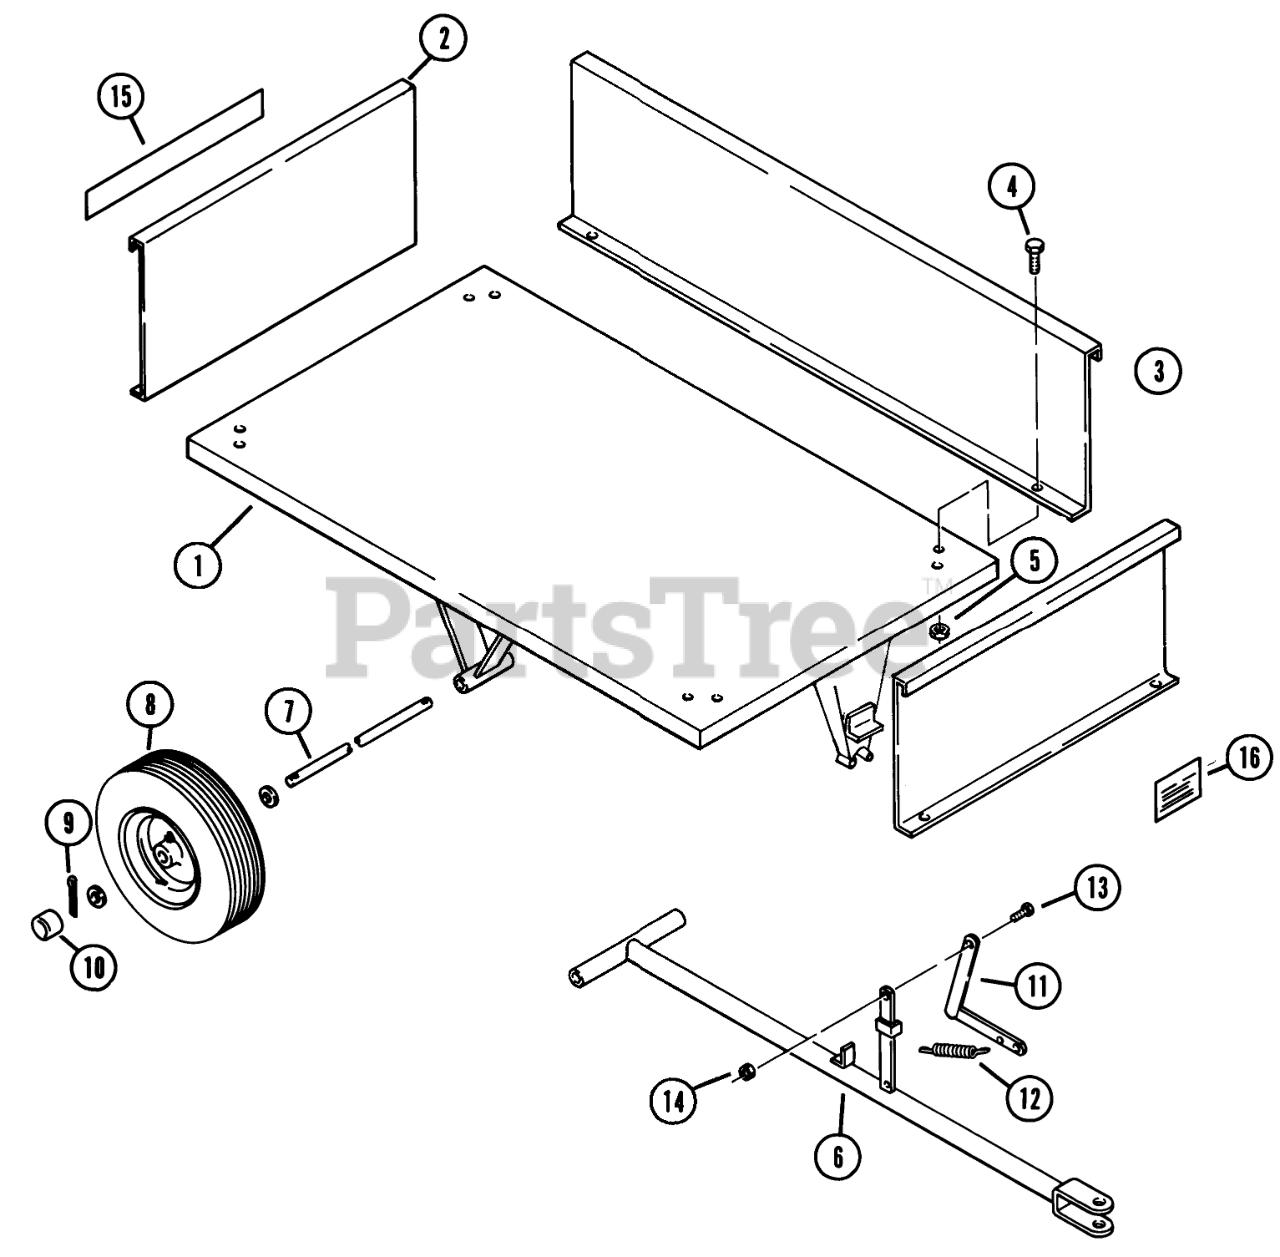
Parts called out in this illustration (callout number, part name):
1	Bed Assembly
2	Front and Rear Gate
3	Side Gate
4	BOLT
5	NUT
6	Drawbar Assembly
8	Wheel Assembly (6.50 x 8-16)
9	Cotter Pin
10	HUB CAP
11	Latch Assembly
12	SPRING
13	Bolt
14	Nut
15	Decal
16	Decal-Caution
